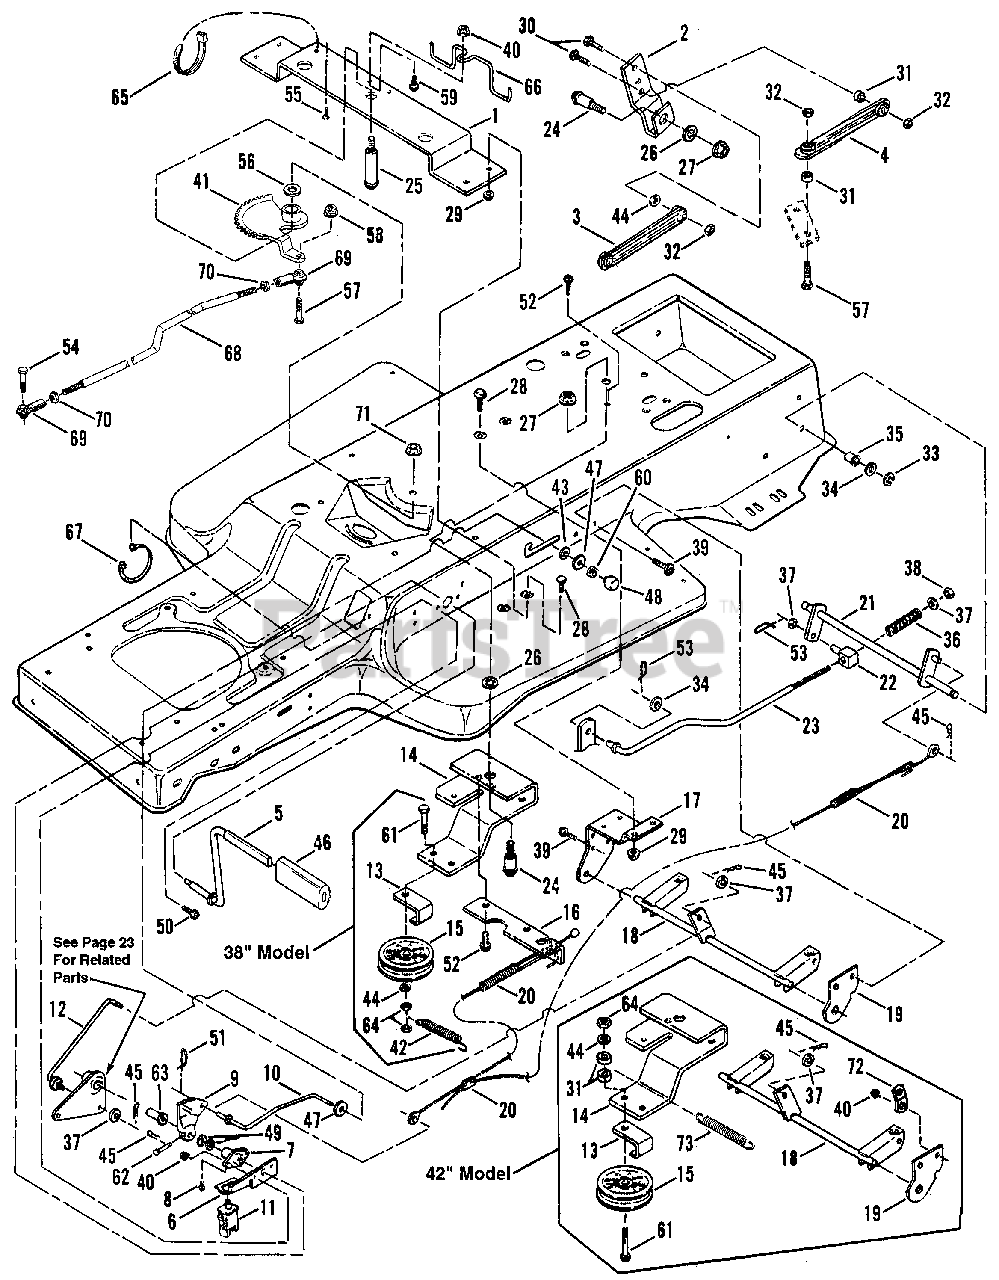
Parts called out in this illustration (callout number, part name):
1	BRACE, Sector Gear
2	BELLCRANK, Shift Lever
3	LINK, Shift Lever
4	LINK, Shift Lever (Twisted) (Short)
4	LINK, Shift Lever (Twisted) (Long)
5	PEDAL, Park Brake
6	BRACKET, Brake Switch
7	ASSEMBLY, Foot Shaft Pivot
8	FITTING, Lube
9	ASSEMBLY, Clutch/Brake Arm
10	LATCH, Park Brake
11	SWITCH
12	ROD, Lift Link
13	GUIDE, Pulley
14	ARM, Idler (Traction Drive)
15	PULLEY
16	EXTENSION, Idler Arm
17	BRACKET, Rear Lift/PTO Lever
18	WELDMENT, Rear Lift
19	BRACKET, Deck Hang Pivot
20	ASSEMBLY, Clutch Brake Cable
21	WELDMENT, Brake Pivot
22	SWIVEL, Brake Link
23	ROD, Brake
24	BOLT, 1/2-13 x 2" Shoulder
25	BOLT, 1/2-13 x 3 7/8" Shoulder
26	WASHER, 1/2 Internal Tooth Lock
27	NUT, 1/2-13 Hex Flange Lock
28	BOLT, 1/4-20 x 5/8" Carriage
29	NUT, 1/4-20 Hex Flange Lock
30	SCREW, 3/8-16 x 1 1/4" Hex Head Cap
31	SPACER
32	NUT, 3/8-16 Hex Center Lock
33	RING, Retaining
34	WASHER, 1/2 Flat
35	BEARING, Nylon
36	SPRING, Brake
37	WASHER, 3/8" Flat
38	NUT, 3/8-16 Hex Nyloc
39	SCREW, 5/16-18 x 5/8" Truss Head (Torx)
40	NUT, 5/16-18 Hex Flange Lock
41	ASSEMBLY, Sector Gear
42	SPRING, Traction Drive
43	RETAINER, 5/16 Bolt
44	WASHER, 3/8 Split Lock
45	HAIRPIN, 3/32 x 1 1/2"
46	PAD, Pedal
47	WASHER, 5/16 Nylon
48	KNOB, Push/Pull
49	WASHER, 5/8 Flat
50	SCREW, 5/16-18 x 7/8" Truss Head (Torx)
51	COTTER-PIN, 3/64 x 1 7/32" (Self-Locking)
52	SCREW, 5/16-18 x 5/8" Self Tapping
53	COTTER-PIN, 1/16" x 1.42" Self-Locking
54	SCREW, 3/8-24 x 1 1/4" Hex Head Cap
55	SCREW, #10-24 x 1/2" Hex Washer Self-Tap (Torx)
56	WASHER, 3/4 Thrust
57	SCREW, 3/8-16 x 1 1/2" Hex Head Cap
58	NUT, 3/8-16 Hex Flange Lock
59	BOLT, 5/16-18 x 3/4" Hex Flange Lock
60	RING, Tolerance
61	SCREW, 3/8-16 x 2 1/4" Hex Head Cap
62	PIN, 3/16 x 1 1/2" Clevis
63	BEARING, Flange
64	NUT, 3/8-16 Hex
65	TIE, Cable
66	GUIDE, Drive Belt
67	TIE, Wire
68	LINK, Drag
69	BALL JOINT, 3/8-24
70	NUT, 3/8-24 Hex Jam
71	NUT, 1/2-13 Hex Center Lock
72	CLIP, Spring
73	SPRING, Idler
